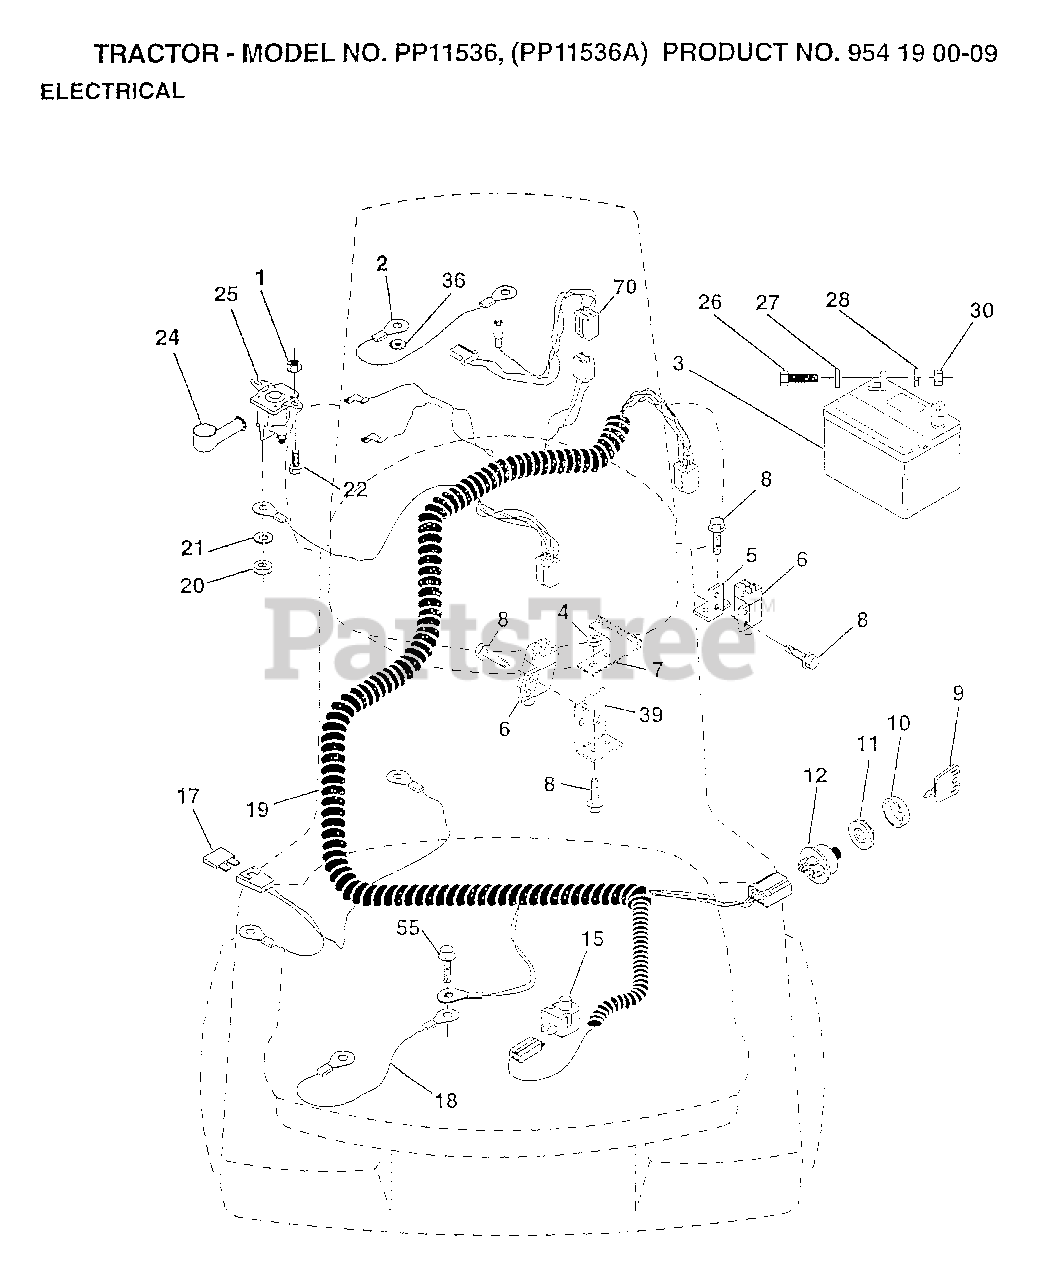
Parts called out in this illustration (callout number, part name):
1	NUT HXKEP 1/4X20
2	CABLE ASM.
4	LOCKNUT
5	BRACKET LT
6	SWITCH INTERLOCKT
7	KEEPER.ACTUAT.LR.
8	SCREW
9	KEY MLD GEN DELTA
10	COVER KEY SWITCH
15	SWITCH SEAT
17	FUSE HYT
18	CABLE ASSY
19	HARNESS.IGN.FEND.
20	NUT
22	BOLT HXHD FIN
25	MANUAL.OP.GEN.RTA
26	BOLT LT
27	WASHER
28	LOCKWASHER
36	LOCKWASHER
39	BRACKET SWT CLUTC
55	SCREW LT
70	HARNESS ENG DUAL
